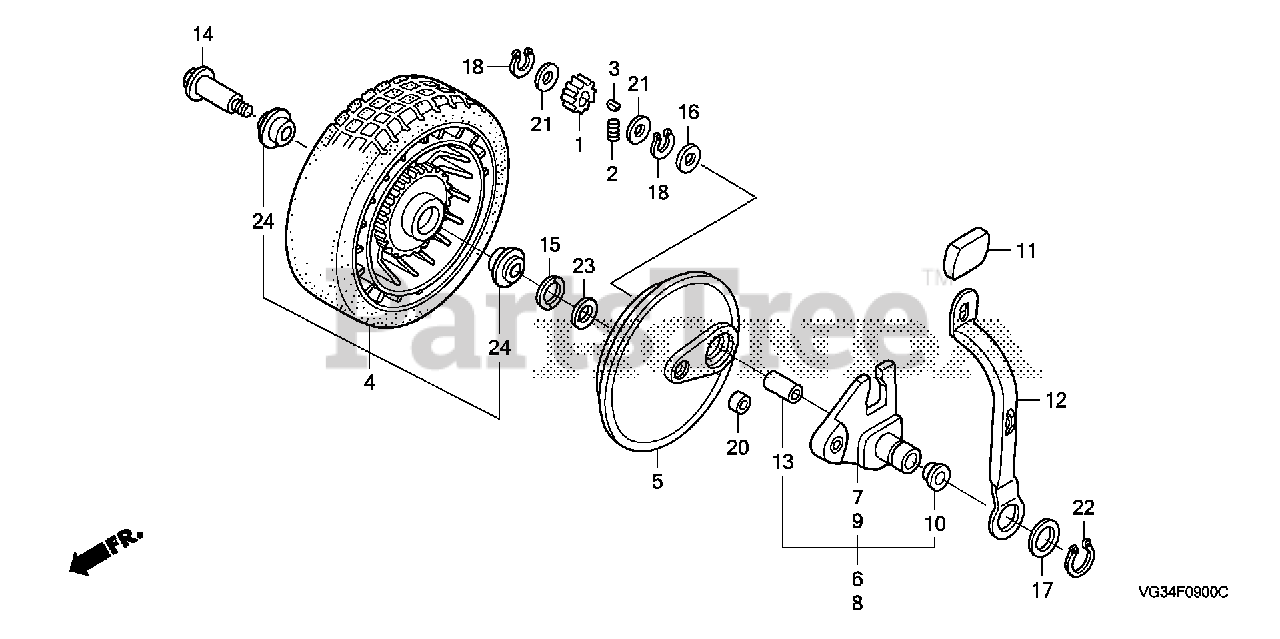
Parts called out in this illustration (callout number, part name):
4	WHEEL, RR.
4	WHEEL *NH164* (GRIP GRAY)
7	ARM, R. RR. ADJUSTER
9	ARM, L. RR. ADJUSTER
11	GRIP, ADJUSTER *NH105* (MAT BLACK)
12	PLATE, RR. ADJUSTER
14	BOLT, RR. WHEEL SHAFT
15	WASHER, WHEEL
17	WASHER, FLAT (26X44)
20	COLLAR, RR. ADJUSTING
22	CIRCLIP (OUTER) (25MM)
24	BEARING, RADIAL BALL
24	BEARING, WHEEL
